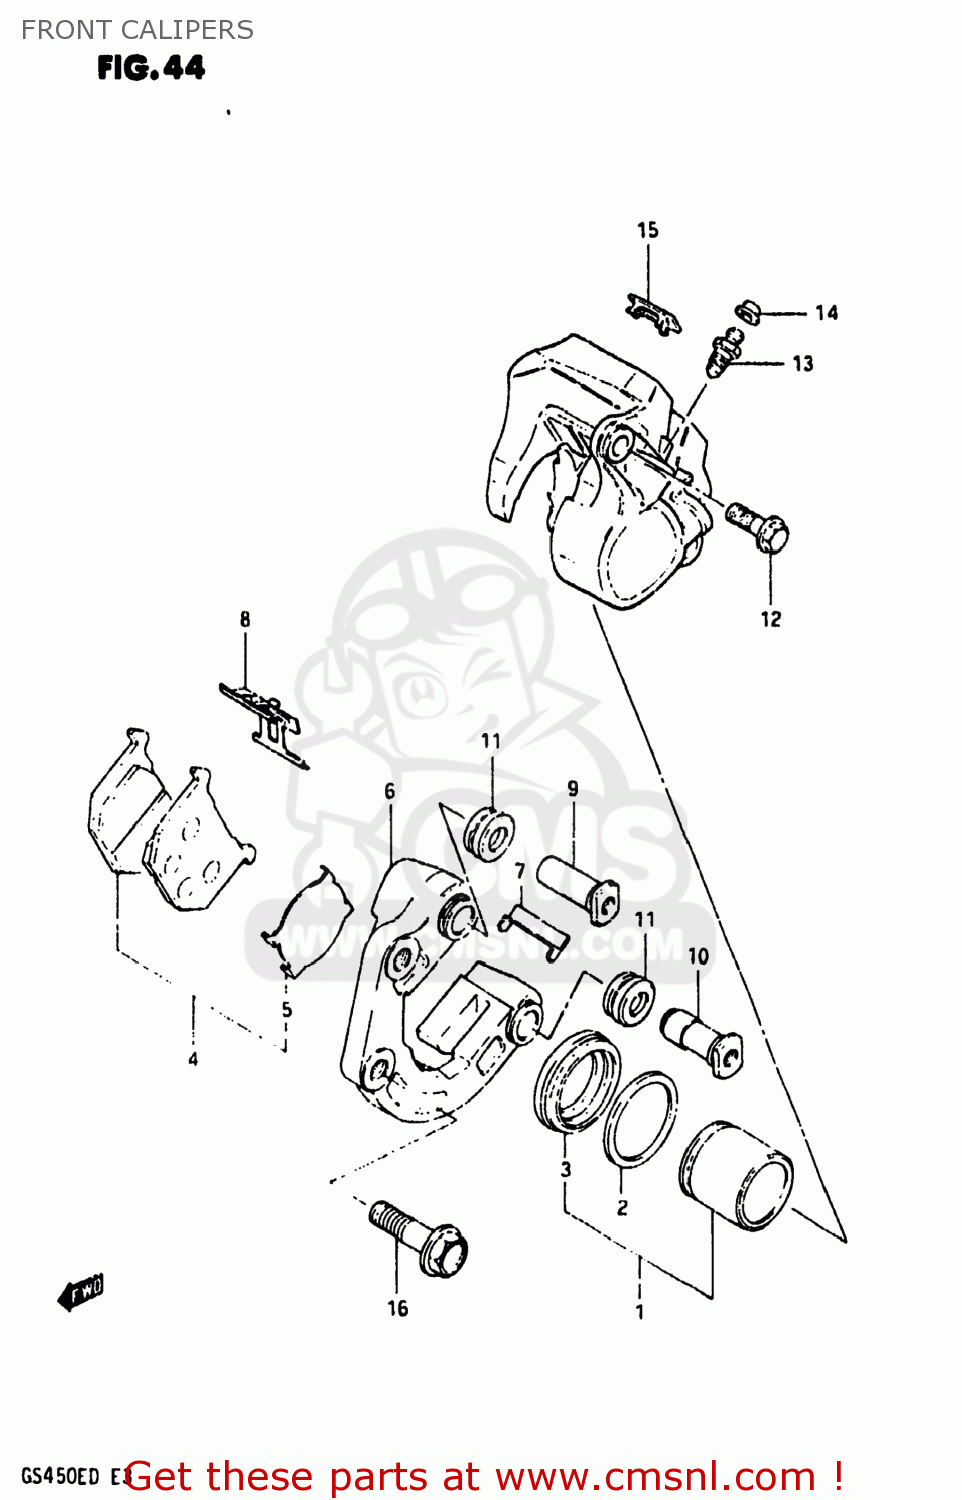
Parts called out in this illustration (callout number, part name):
1	PISTON SET
2	SEAL,FR CALIPE
3	BOOT,PISTON
4	PAD SET,BRAKE (MCA)
5	SHIM,PAD
6	CARRIER,CALIPER,LEFT
7	GUIDE,PAD
8	SPRING,PAD
9	AXLE NO.1
10	AXLE NO.2
11	BOOT,AXLE
12	BOLT
13	BLEEDER
14	CAP,BREATHER
15	COVER
16	BOLT 10X37
